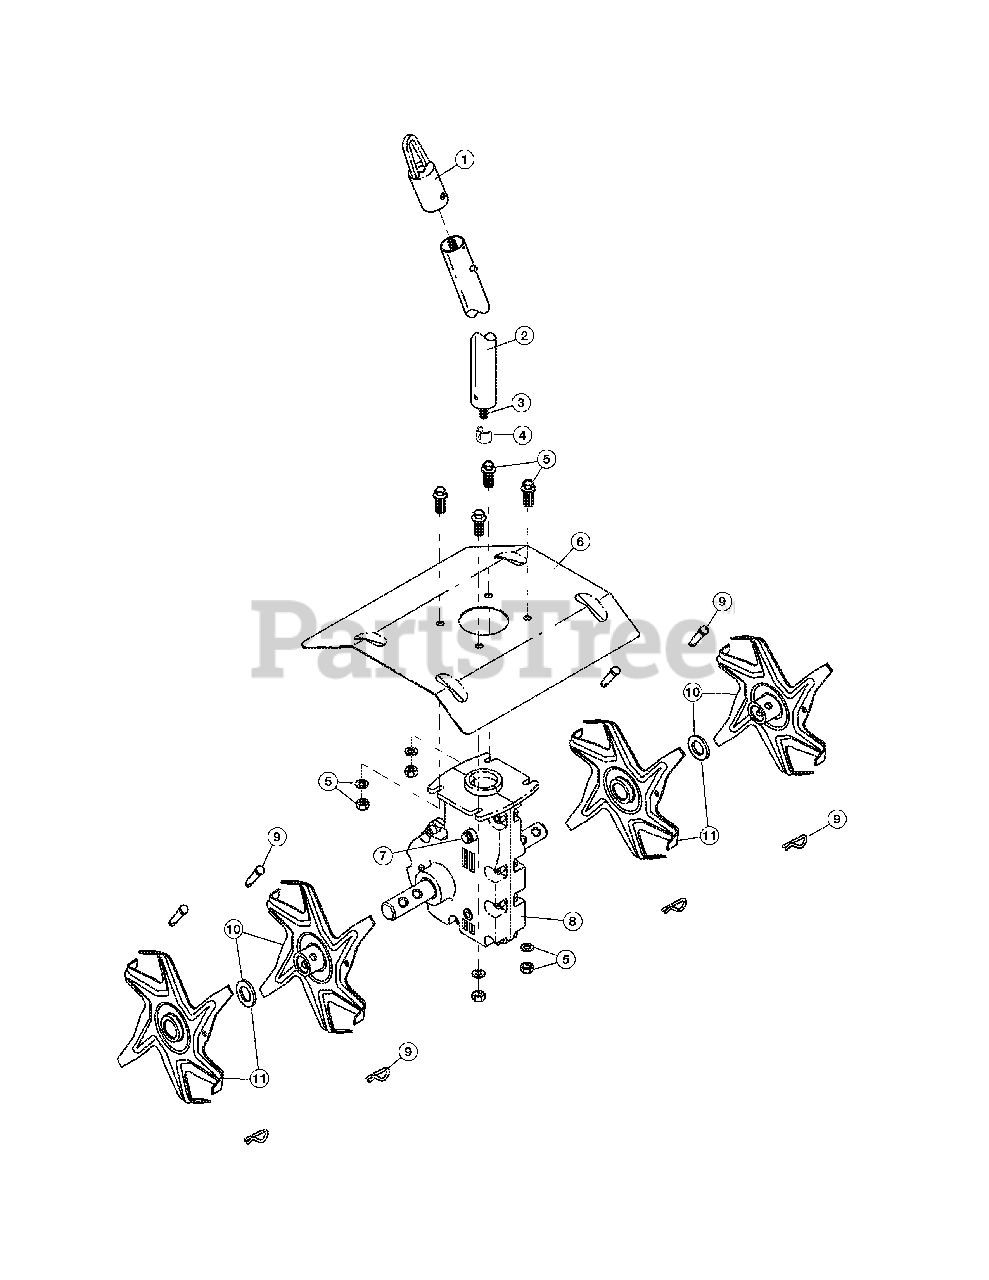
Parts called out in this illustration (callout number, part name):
1	Accessory Hanger
2	Drive Shaft Housing Assembly
3	Flexible Drive Shaft
4	Retainer Sleeve
5	Guard Mounting Hardware Set
7	Bolt
8	Gear Box Assembly
9	Tine Fastener Assembly
10	Tine Assembly (Left Outer or Right Inner)
11	Tine Assembly (Left Inner or Right Outer)
